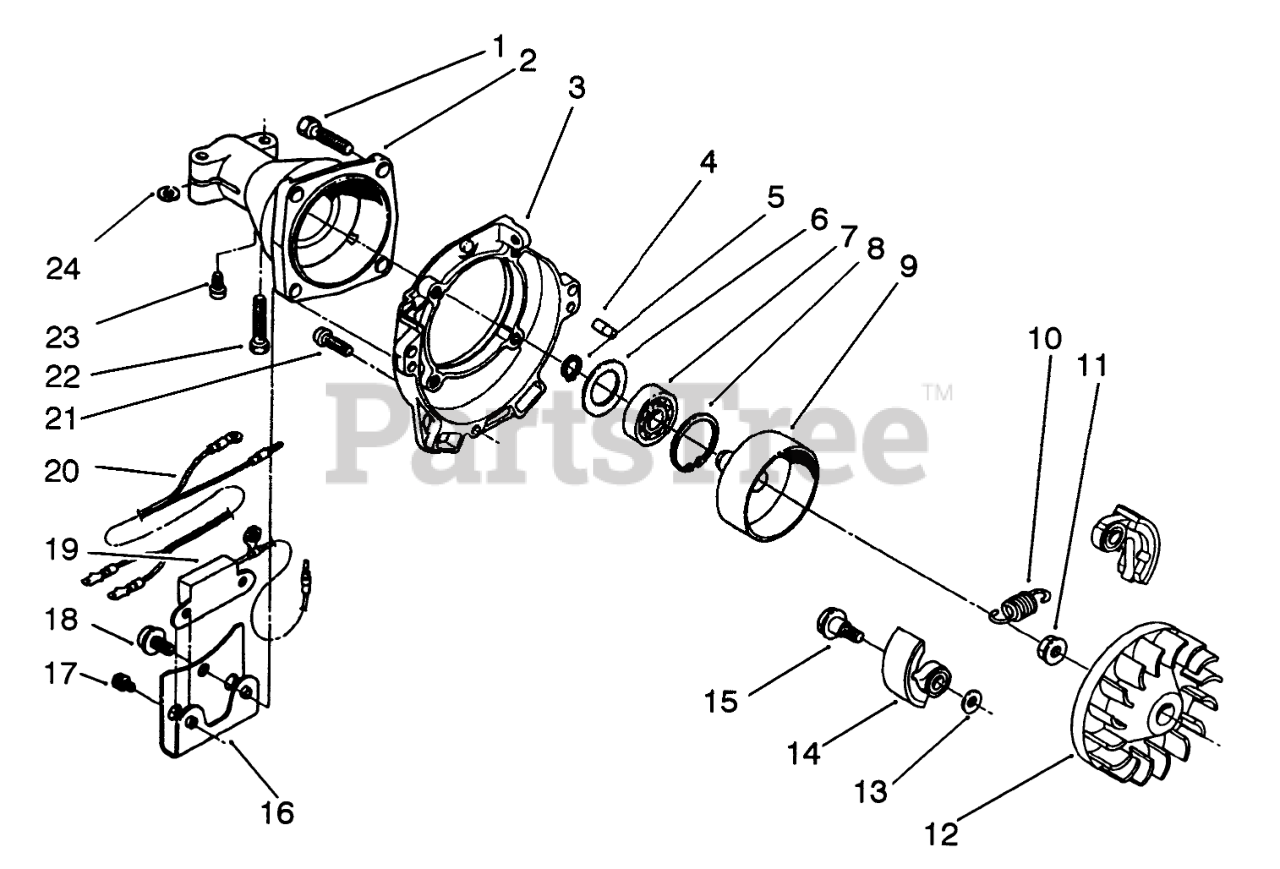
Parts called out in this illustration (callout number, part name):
1	Bolt/Washer
2	CLUTCH CASE
3	FAN CASE
5	SNAP RING
6	Washer
7	BALL BEARING
8	SNAP RING
9	CLUTCH DRUM
10	SPRING
13	WASHER
14	SHOE, CLUTCH
15	CLUTCH BOLT
16	Bracket-Unit
17	SCREW W/ WASHER
18	SCREW & WASHER
19	TRANSISTOR
20	WIRE,LEAD
21	BOLT & WASHER
22	BOLT-WASHER/ENG
23	Screw/Washer
24	WASHER
